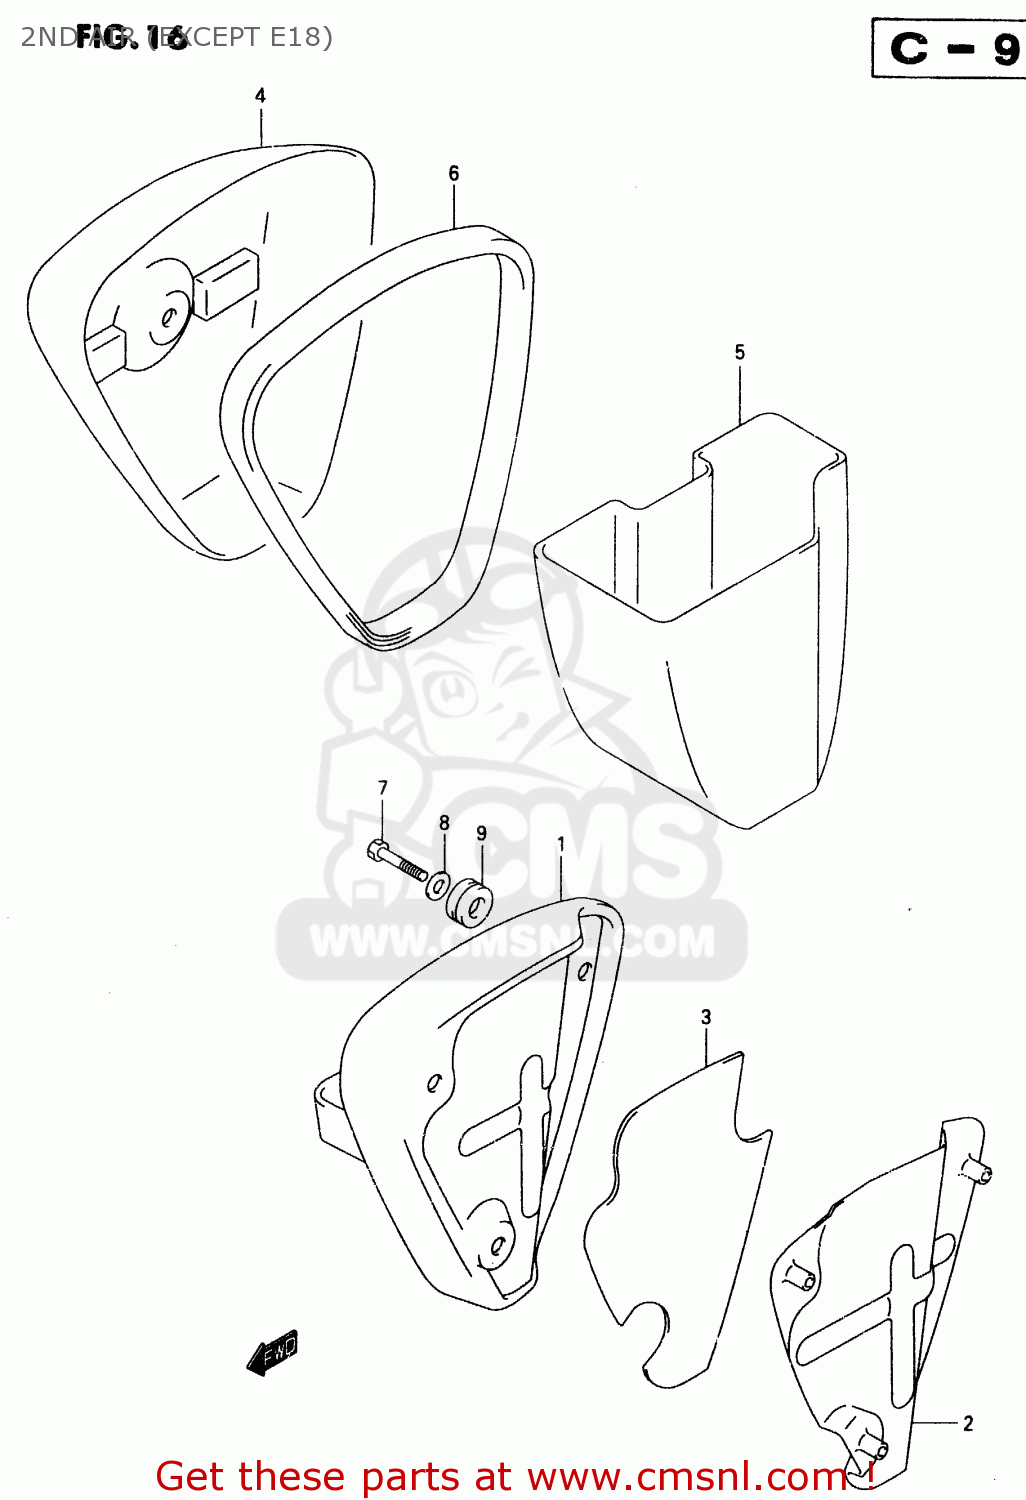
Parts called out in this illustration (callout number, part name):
1	BRACKET,2ND AIR SPRT
2	PLATE,2ND AIR HEAT GUARD
3	SHEET,2ND AIR HEAT GUARD PLATE
4	COVER ASSY,2ND AIR
5	HOLDER,2ND AIR
6	CUSHION
7	BOLT
8	WASHER
9	CUSHION
